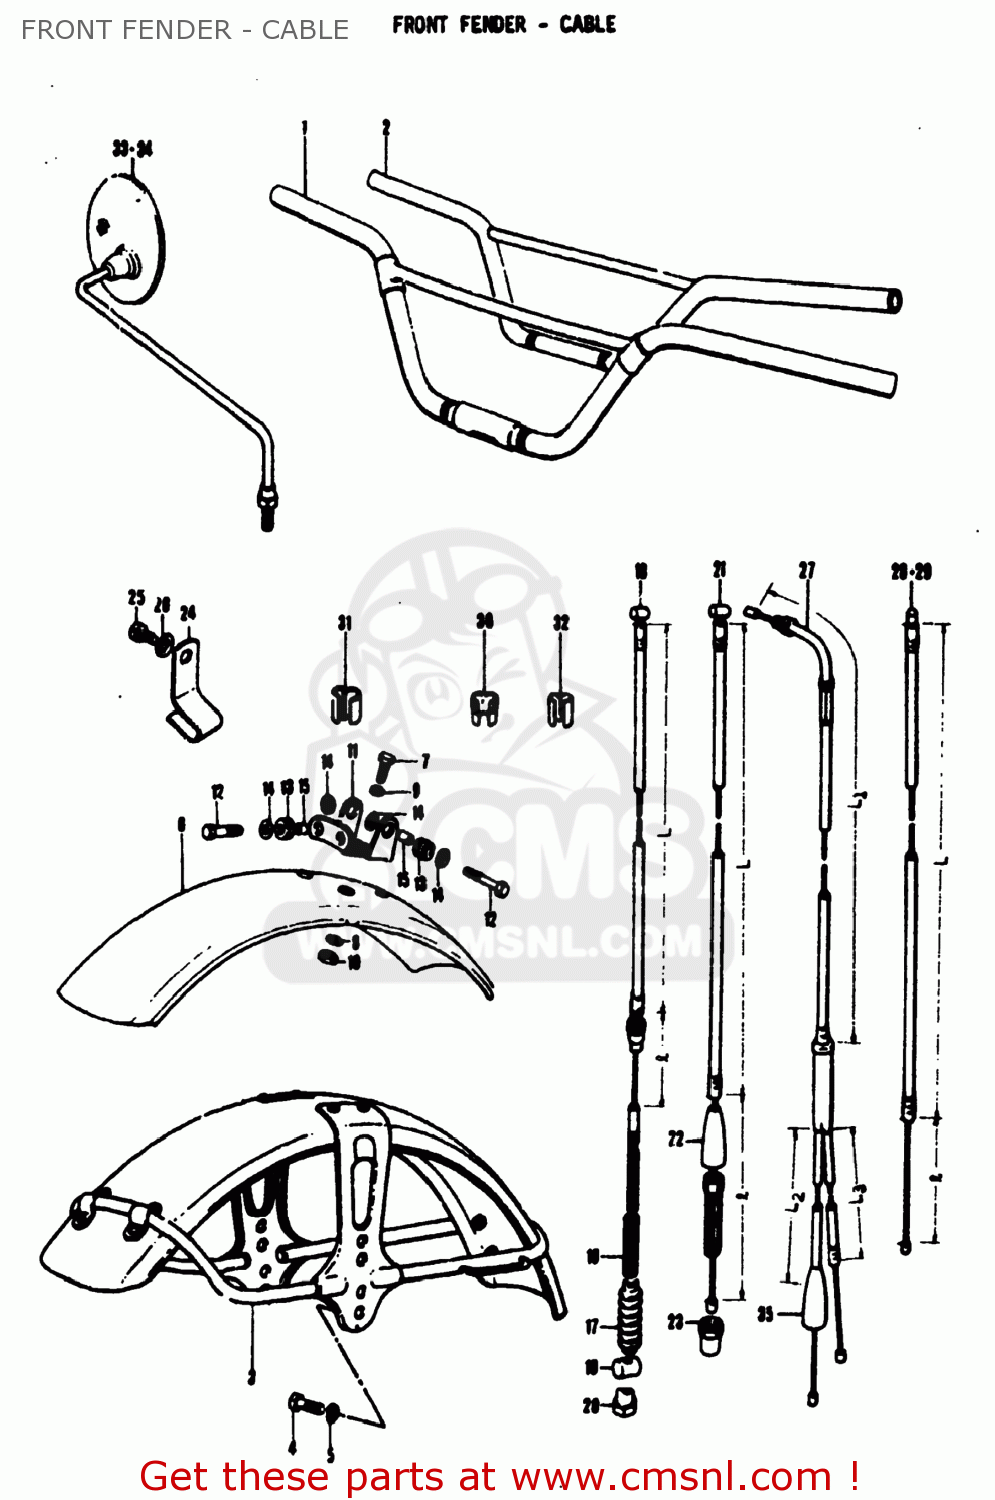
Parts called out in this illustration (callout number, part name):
1	HANDLEBAR
2	HANDLEBAR
3	FENDER,FRONT
4	BOLT
5	LOCK WASHER
6	FENDER,FRONT
7	BOLT
8	LOCK WASHER
9	WASHER
10	NUT
11	BRACE,FRONT FENDER
12	BOLT
13	CUSHION
14	WASHER (6.5X20X1.2)
15	SPACER (7X9X7)
16	CABLE ASSY,FR BRAKE(L:1175)
17	SEAL,DUST(7X16X75)
18	SPRING
19	PIN,10X19
20	NUT
21	CABLE ASSEMBLY,CLUTCH
22	SEAL,DUST(7X18X30)
23	NUT
24	CLAMP
25	BOLT
26	LOCK WASHER
27	CABLE ASSEMBLY,THROTTLE
28	CABLE ASSEMBLY,STARTER
29	CABLE COMP,STARTER
30	CLIP
31	CLIP
32	CLIP
33	MIRROR ASSEMBLY,LEFT
34	MIRROR ASSEMBLY,RIGHT
35	SEAL,DUST(7X18X30)
